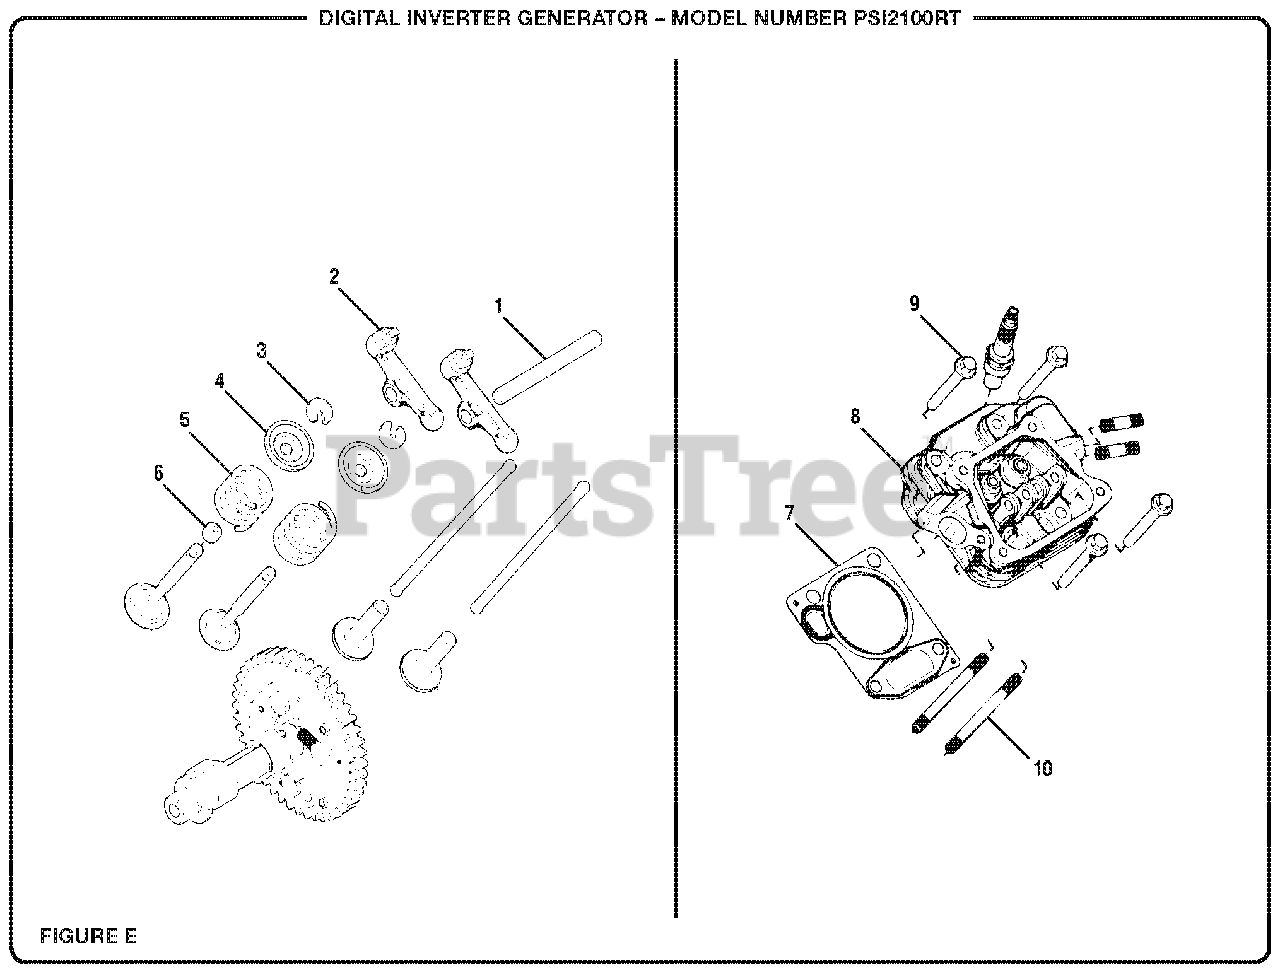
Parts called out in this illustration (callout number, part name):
1	Valve Rocker Arm Shaft
2	Valve Rocker Arm Set
4	Valve Spring Retainer
5	Valve Spring
6	Valve Oil Seal
7	Gasket, Cylinder Head
8	Cylinder Head Set
9	Bolt (M6x50, Flange)
10	Stud Bolt, Carburetor
